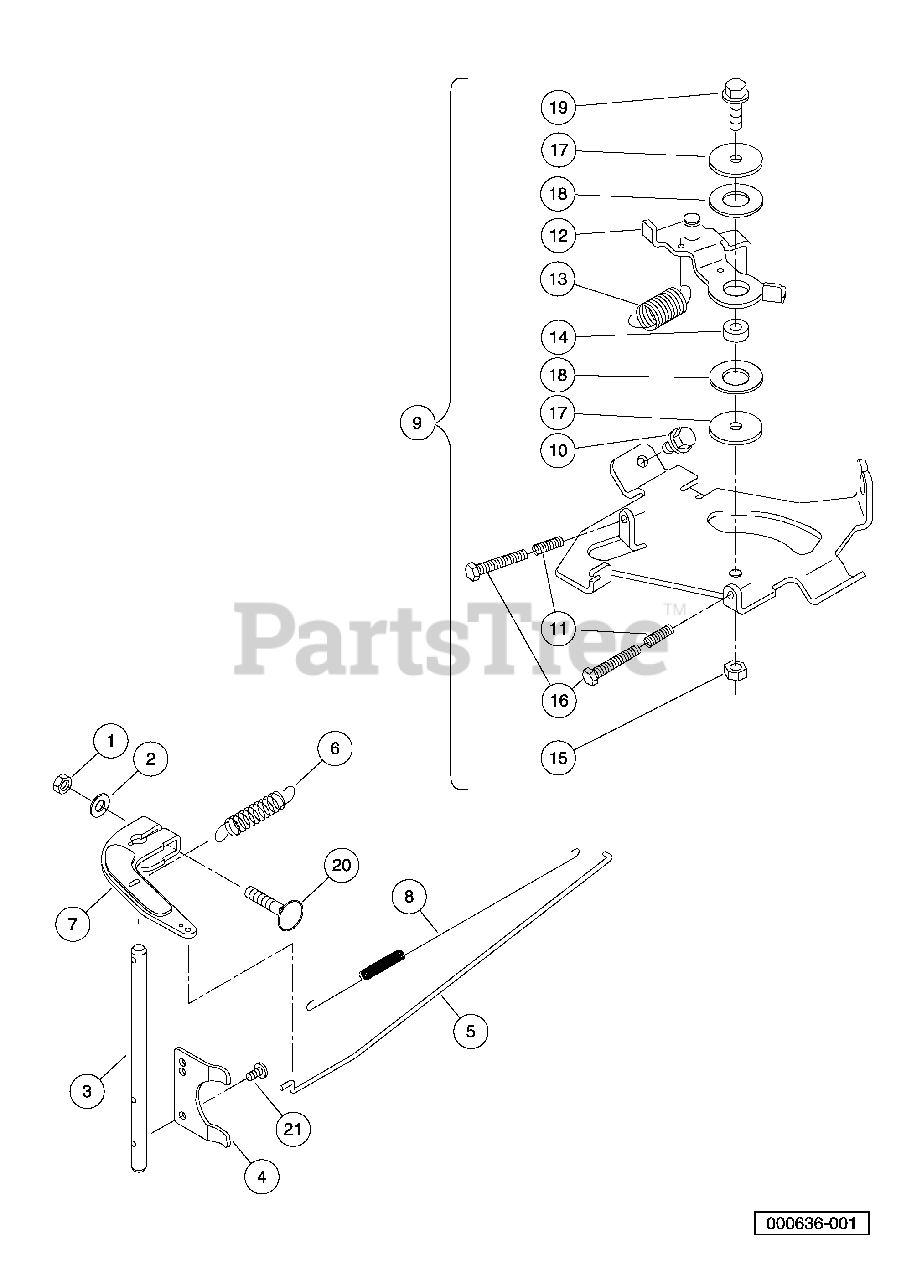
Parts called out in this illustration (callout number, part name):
2	Washer, M6 Flat
3	Shaft, Governor, Fh
4	Plate, Governor, Fh
5	Link, Arm, Governor, Fh
6	Spring, Governor, Fh
7	Arm, Governor, Shaft
8	Spring, Arm, Governor, Fh
9	Panel, Control, Complete, Fh
10	Bolt, Flg, M6 X 1.0 X 12
11	Spring, Fh
12	Lever, Governor, Control, Fh
13	Spring, Governor Return, Fh
14	Collar, Governor, Fh
15	Nut, Governor, Fh
16	Bolt, Speed Control, Fh
17	Washer, Governor, Lower, Fh
18	Washer, Governor, Middle, Fh
19	Bolt, Flanged, M6 X 20, Kaw
20	Bolt, M6 X 35, Kawasaki
21	Screw, Pan, Governor, Fh
